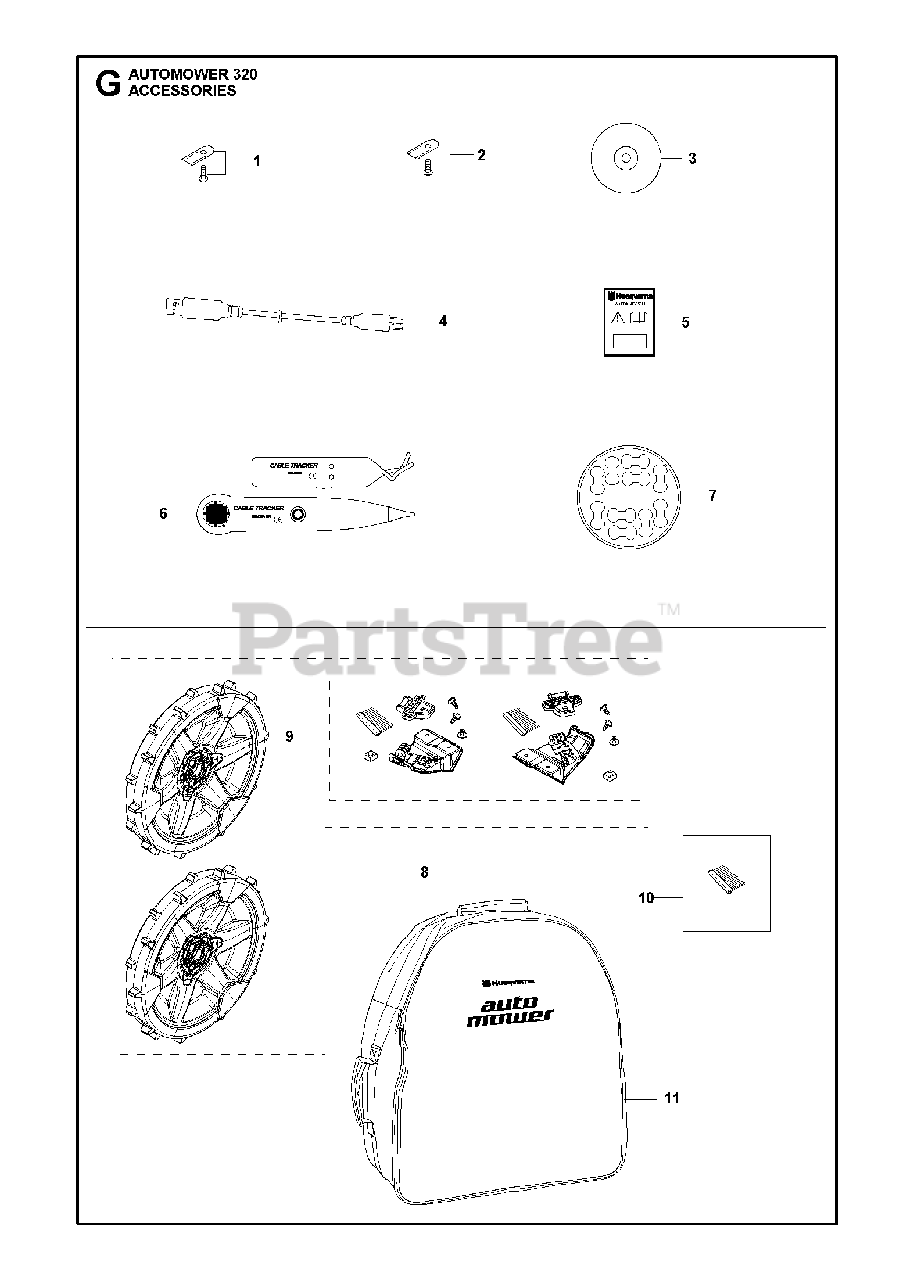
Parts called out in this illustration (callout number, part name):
1	BLADE
1	BLADE KIT
1	BLADE - 30 PCS
1	BLADE - BULK PACK 500 PCS
2	BLADE 9PCS EXTRA THICK
2	Blade Set, 9 Piece Extra Thick
2	BLADE CARBON STEEL, THICK BLAD
2	BLADE 300PCS -SINGLE HOLE THIC
5	LABEL WARRANTY SEAL DEALER
5	LABEL WARRANTY SEAL KIT 10 PK
6	TEST EQUIPMENT
